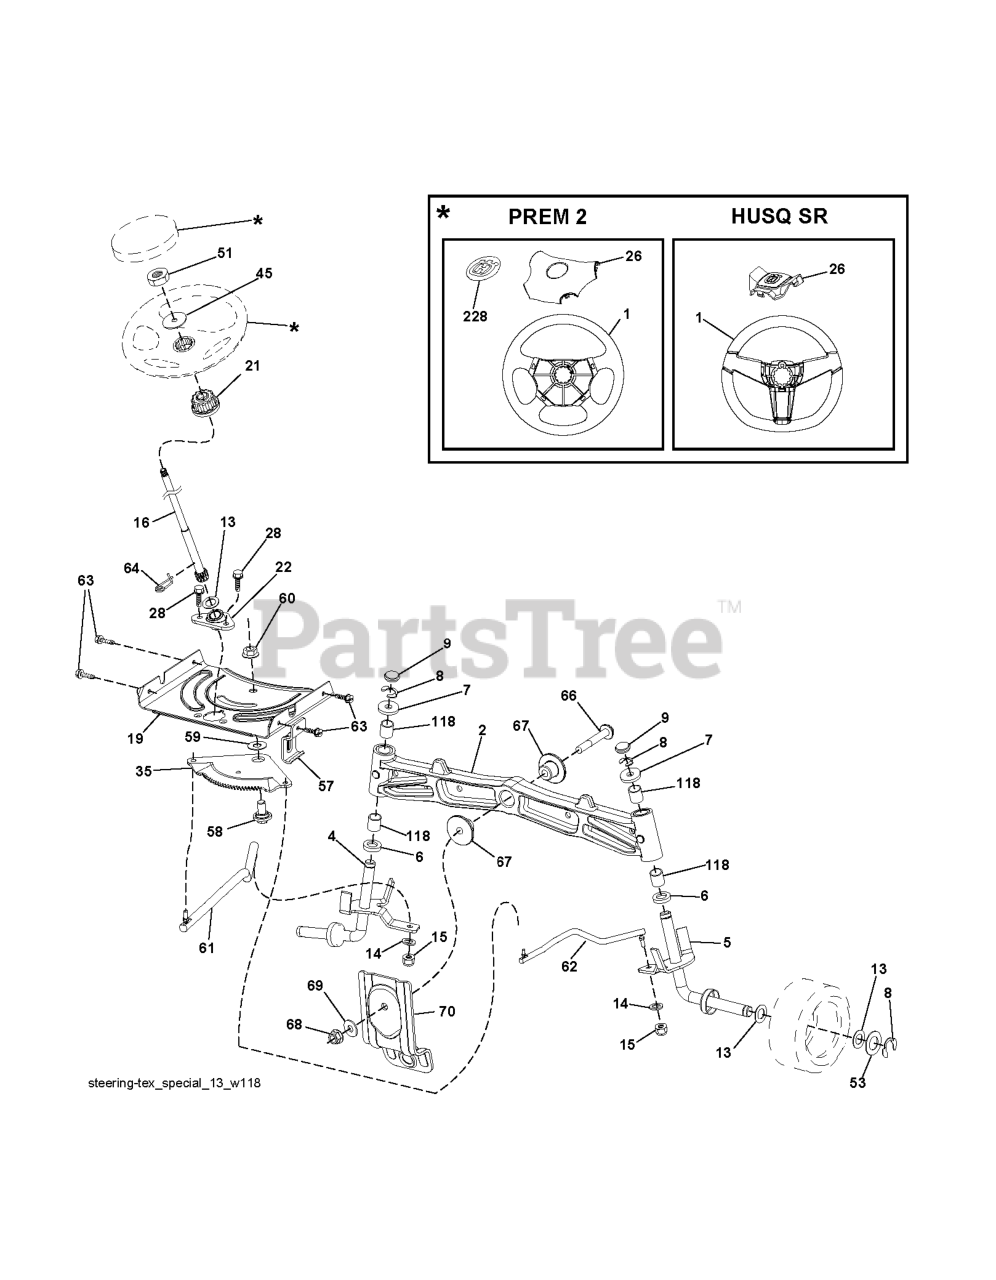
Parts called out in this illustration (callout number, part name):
1	RP WHEEL.STEER.HUSQ.PREM.OVMLD
2	AXLE.CAST.IRON
4	SPINDLE.WELDED.LH.16"TEX
5	SPINDLE.WELDED.RH.16"TEX
6	THRUST WASHER
9	CAP.SPINDLE.BLACK
14	WASHER, LOCK 3/8
15	NUT CROWNLOCK 3/8-24
16	SHAFT.STEER.STEALTH.DD
19	PLATE.STEER.DDL.NLT/NG
21	ADAPTER, WHEEL STNG..
22	BUSHING.ASM.STEERING.A
26	RP INSERT.CAP.WHL.STRG.HUSQ.
28	SCREW, 3/8-16X3/4
35	GEAR.SECTOR.PLATE.DDL.
45	WASHER 9/16"ID, 2 3/8"OD
51	NUT.HEX.1/2-20
53	WASHER.HARDENED
57	BRKT.UPSTOP.GT/LT.TEX
58	BOLT.SHOULDER.SECTOR.P
59	WASHER.THURST.SECTOR.S
60	NUT FLANGE LOCK 5/8-11
61	DRAGLINK.LH.BALLSTUD.D
62	DRAGLINK.RH.BALLSTUD.D
63	SCREW
64	RETAINER.CLIP.SPRING.S
66	BOLT HEX FGHD 7/16-14 X 3 SERR
67	BUSHING.PM.FRONT AXLE
68	NUT.LOCK.FLANGE.7/16
69	WASHER.1.5X.505X.118
70	BRKT.DECK.SUSPENSION.F
118	BUSHING, AXLE CAST
228	DECAL.WHEEL.STRG.LGN.H
